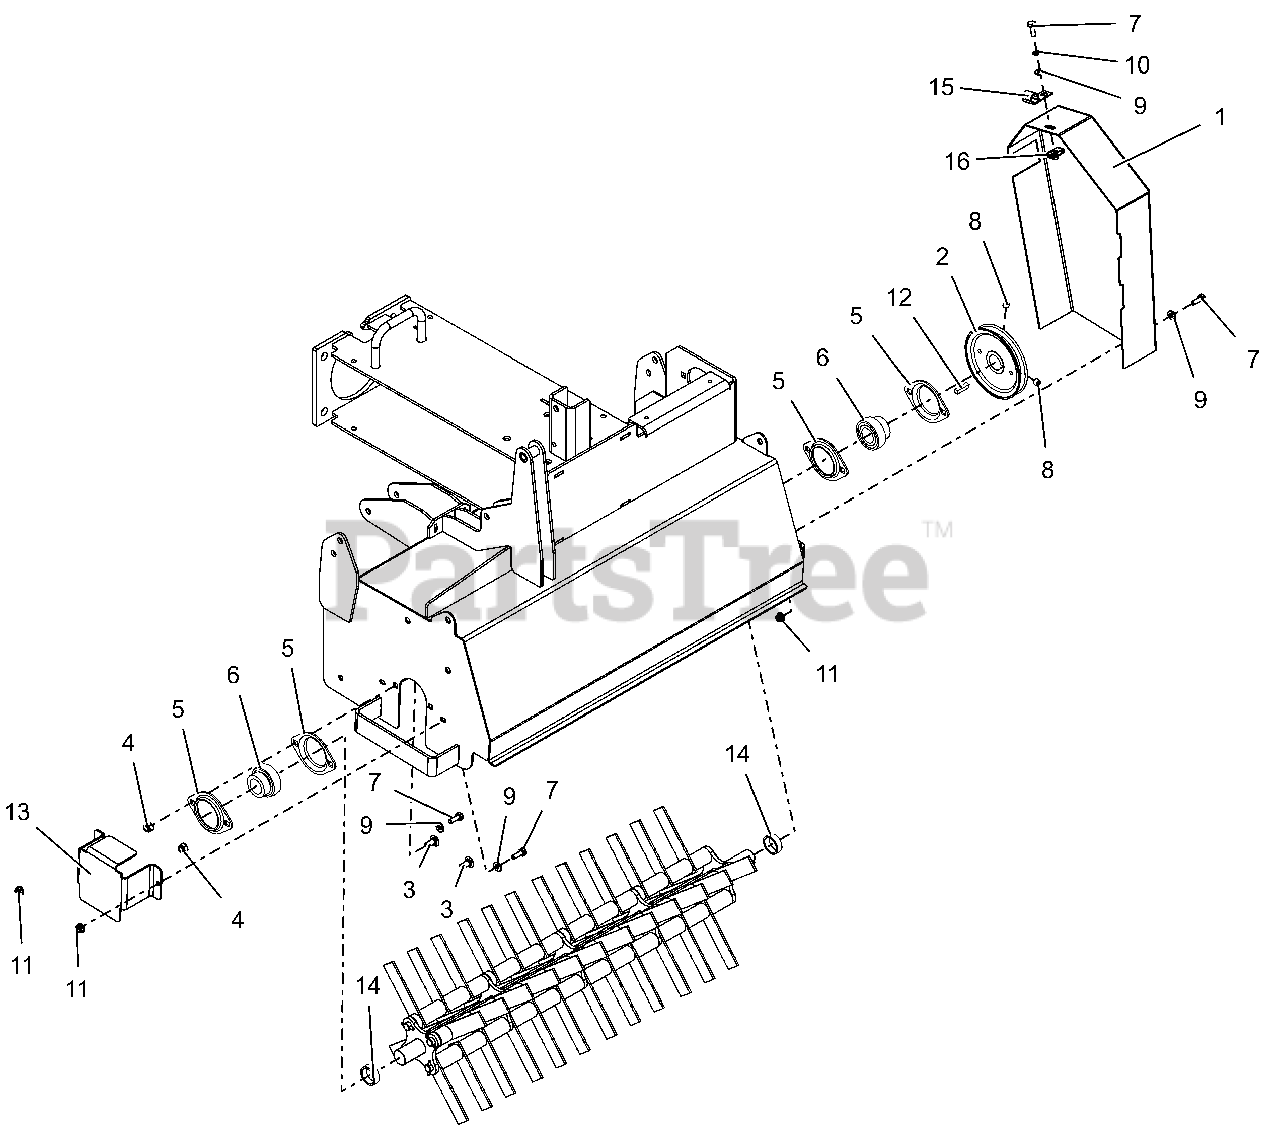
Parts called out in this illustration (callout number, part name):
1	BELT SHIELD WLDMT W/SAFETY DECALS
2	WLDMT, PULLEY 4.75 IN
3	BLT, RHSSN.31-18X.750 G5 ZCC
4	NUT,NYL .31-18 G5 ZCC
5	MTG-FLG 2 HOLE 52MM X 3.75
6	BRG/W COLLAR 1.0 X 2.047 X.844
7	BLT, HEX .25-20X.75 G5 ZCC
8	SET SCREW, 3/8-24 X 3/8 (CUP)
9	WSHR,FLT .281X.625X.065 ZCC
10	WSHR,LK-REG .250X.062 ZCC
11	NUT,NYL-FLG .25-20 GF ZCC
12	KEY, SQ .25X.25X1.00 RC 40-50
13	COVER, END
14	SPCR, 1.25 X .406
15	P-CLIP, .500 INSULATED
16	NUT-RTNR .25-20X.56
